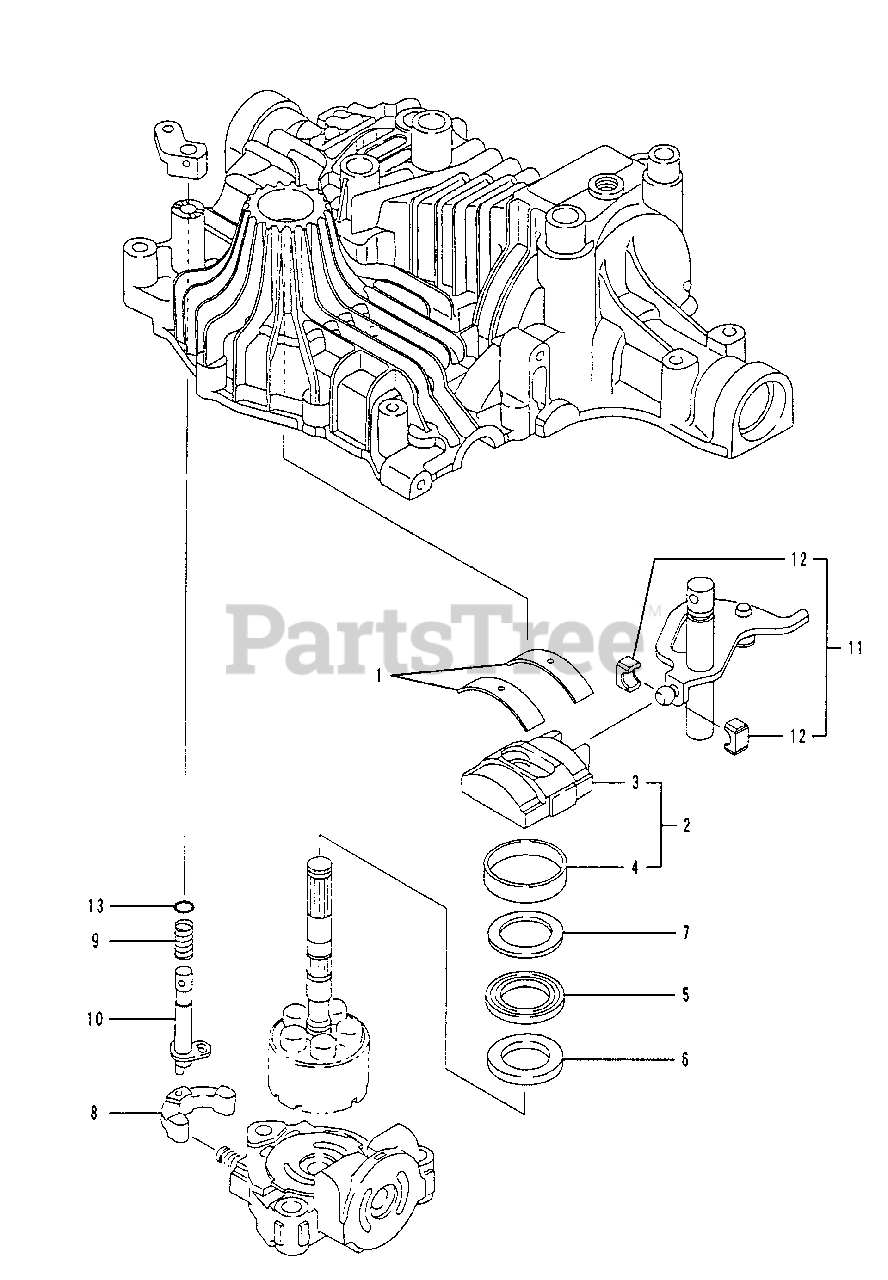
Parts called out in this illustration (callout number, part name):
1	THRUST METAL
2	SWASH PLATE CMP
3	SWASH PLATE
4	SWASH PLATE BUSHING
5	BEARING K81106
6	THRUST PLATE (A
7	THRUST PLATE (B
10	SHAFT (BYPASS
12	BLOCK (SHIFT
13	PACKING P 7
